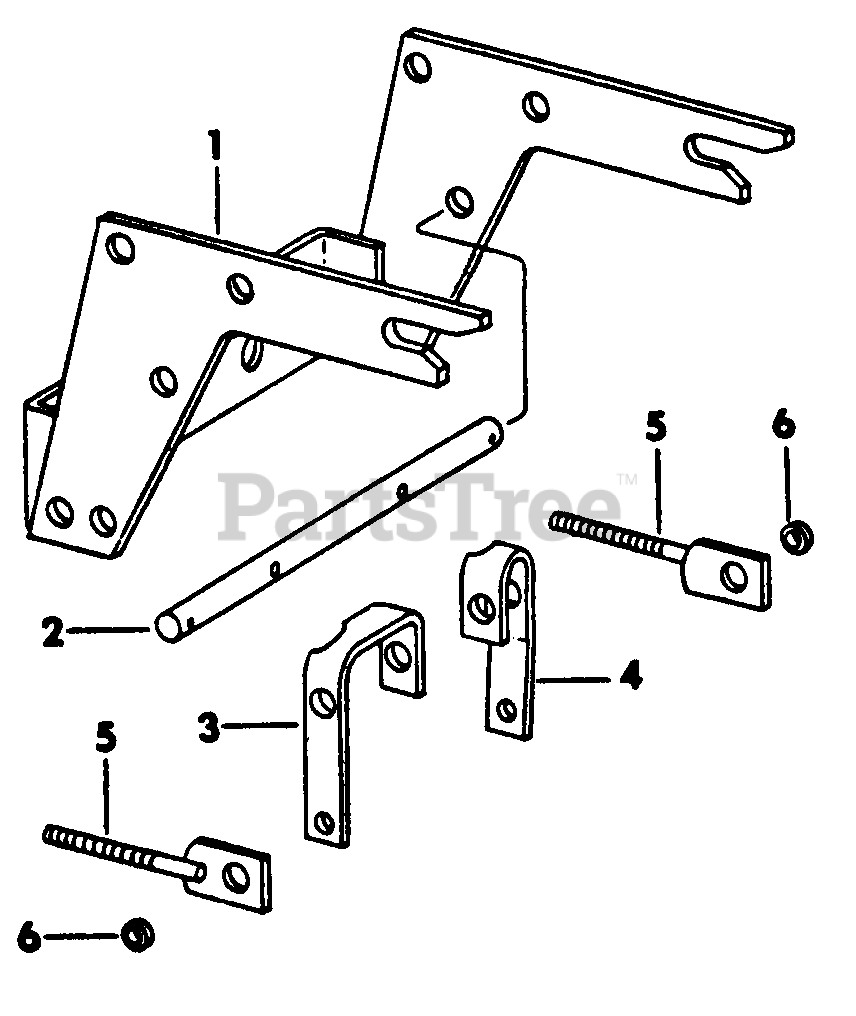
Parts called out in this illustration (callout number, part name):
1	Hanger Assy, Front
2	Rod, Front Mounting
3	Support, Idler LH
4	Support, Idler RH
5	Bracket Assy, Idler Adjuster
6	Spacer, Idler Adjuster
IH-17433-R1	Bolt, 1/2-13 X 1 C-Z Hex-Hd Mach
